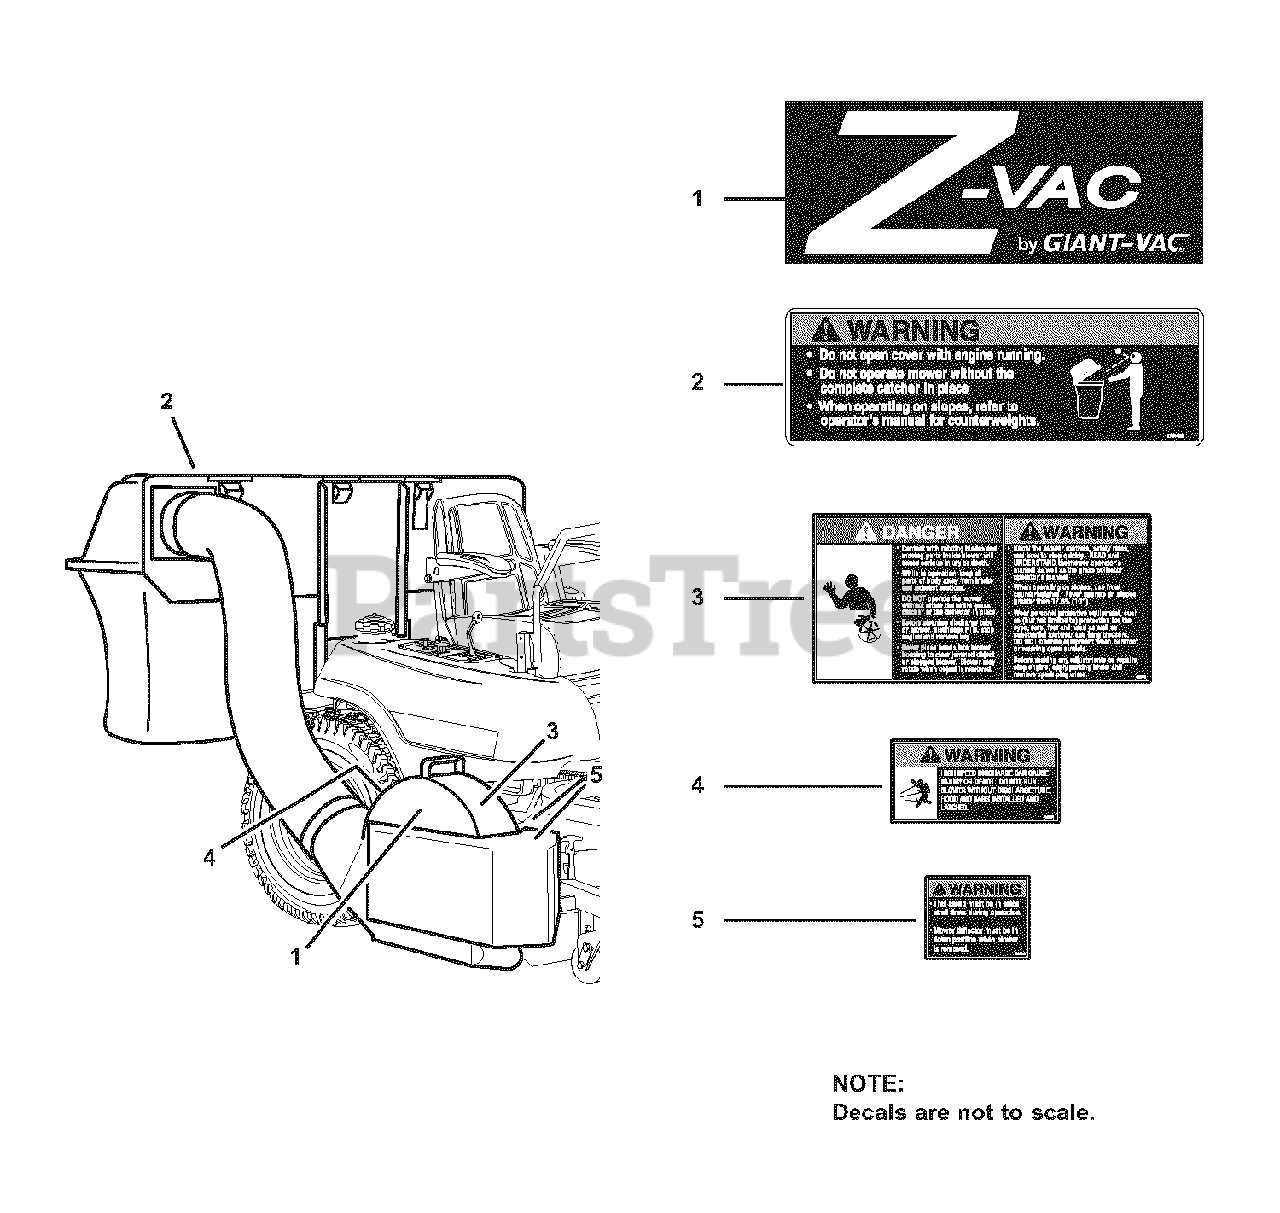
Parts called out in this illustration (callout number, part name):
1	DECAL, Z-Vac
2	DECAL, Safety, Grass Bag
3	DECAL, Danger, Fast-Vac
4	DECAL, Warning, Fast Vac
5	DECAL, Warning, Fast-Vac
